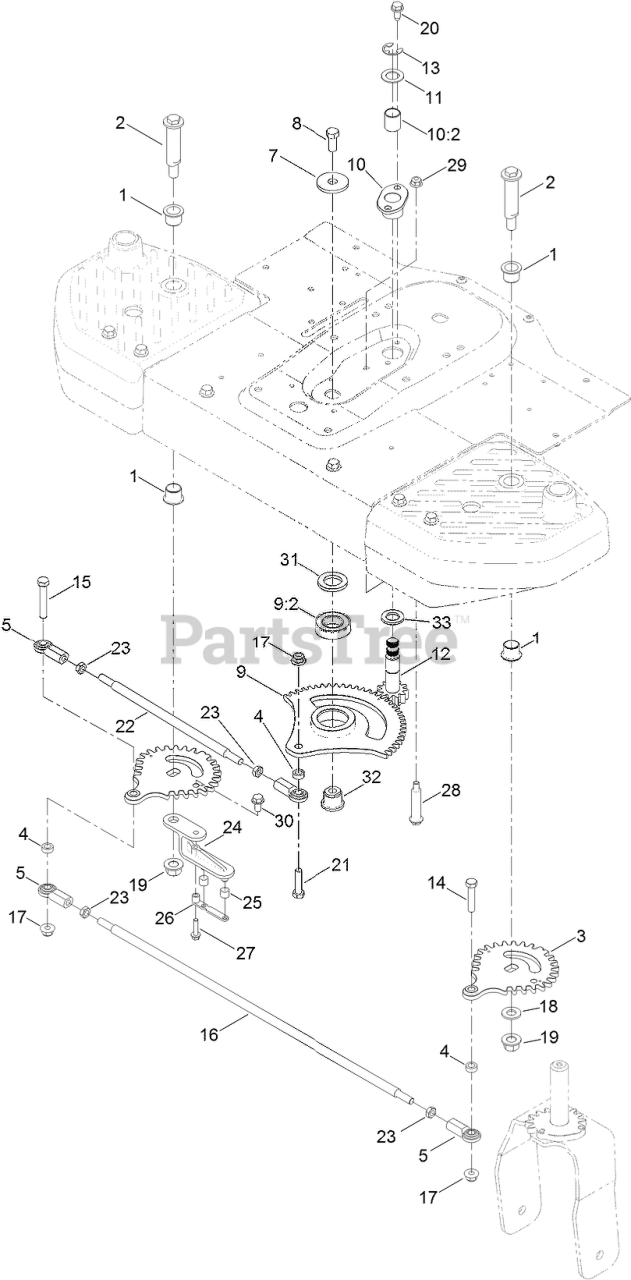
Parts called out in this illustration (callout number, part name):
1	BEARING-FLANGE, IGLIDE
2	BOLT-SHOULDER
3	GEAR-WHEEL, 30 TEETH
4	SPACER
5	JOINT-BALL, END
7	WASHER-THRUST
8	SCREW-HH
9	SECTOR GEAR ASM
9:2	BEARING-BALL
10	FLANGE BEARING ASM
10:2	BUSHING-STRAIGHT
11	WASHER-THRUST
12	LOWER STEERING SHAFT ASM
13	E-RING
14	SCREW-HH
15	SCREW-HH
16	ROD-CROSS, WIDE
17	NUT-HF, NI
18	WASHER-FLAT
19	NUT-LOCK
20	SCREW-HWHTF
21	SCREW-HH
22	ROD-STEERING, WIDE
23	NUT-HJ
24	LEVER-CABLE
25	BUSHING
26	STRAP-ROLLER
27	SCREW-HWHTF
28	BOLT-SHOULDER
29	NUT-HF, NI
30	SCREW-HWHTF
31	SPACER-BEARING
32	PIVOT-BEARING
33	WASHER
